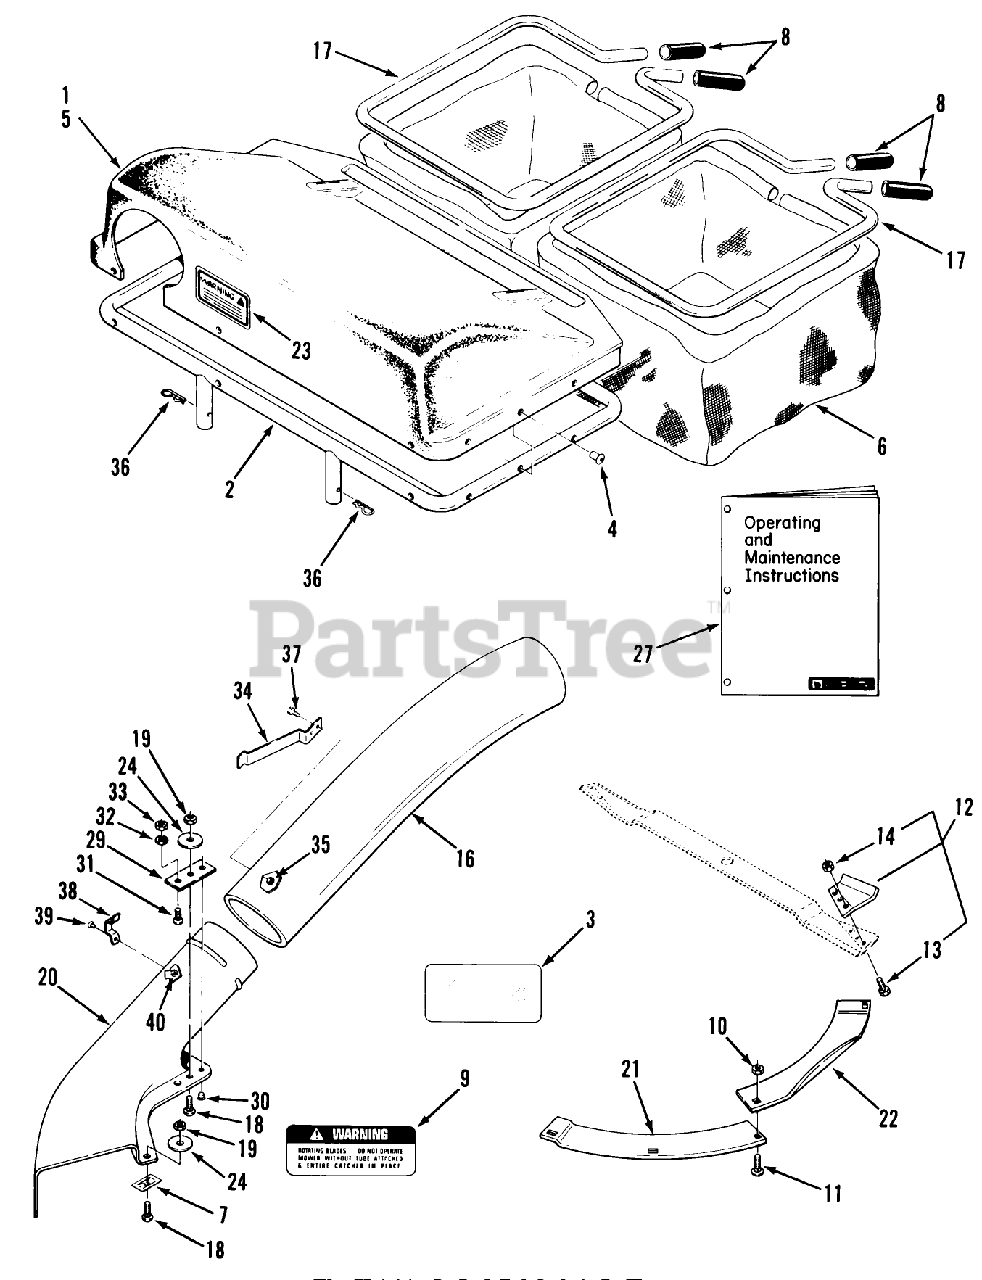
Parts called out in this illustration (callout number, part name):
1	Top Assembly (Includes Items 2, 4 & 5)
2	Frame
3	DECAL-OVERLAY
4	RIVET
6	Bag
7	SPEED NUT 1/4-20
8	GRIP
9	Decal-Warning
10	Nut
11	Bolt
12	Lift Tab Kit (Includes 13 & 14)
13	BOLT 5/16-18X5/8
14	NUT-LOCK 5/16-18
16	TUBE-BAGGER
17	Bag Frame
18	Bolt-Carriage
19	Nut
20	Elbow Assy (Includes Items 29-33, 38, 39 & 40)
21	PLATE MOWER RING B (NS)
22	PLATE MOWER B
23	DECAL-WARNING
24	WASHER
27	Operating and Maintenance Instructions
29	PLATE
30	RIVET -4
31	Screw
32	Lockwasher
33	Hex Nut
34	SPRING-TUBE
35	Nut
36	Pin-Cotter
37	Screw
38	BRACKET
39	Poprivet 5/32 x .379
40	WASHER
